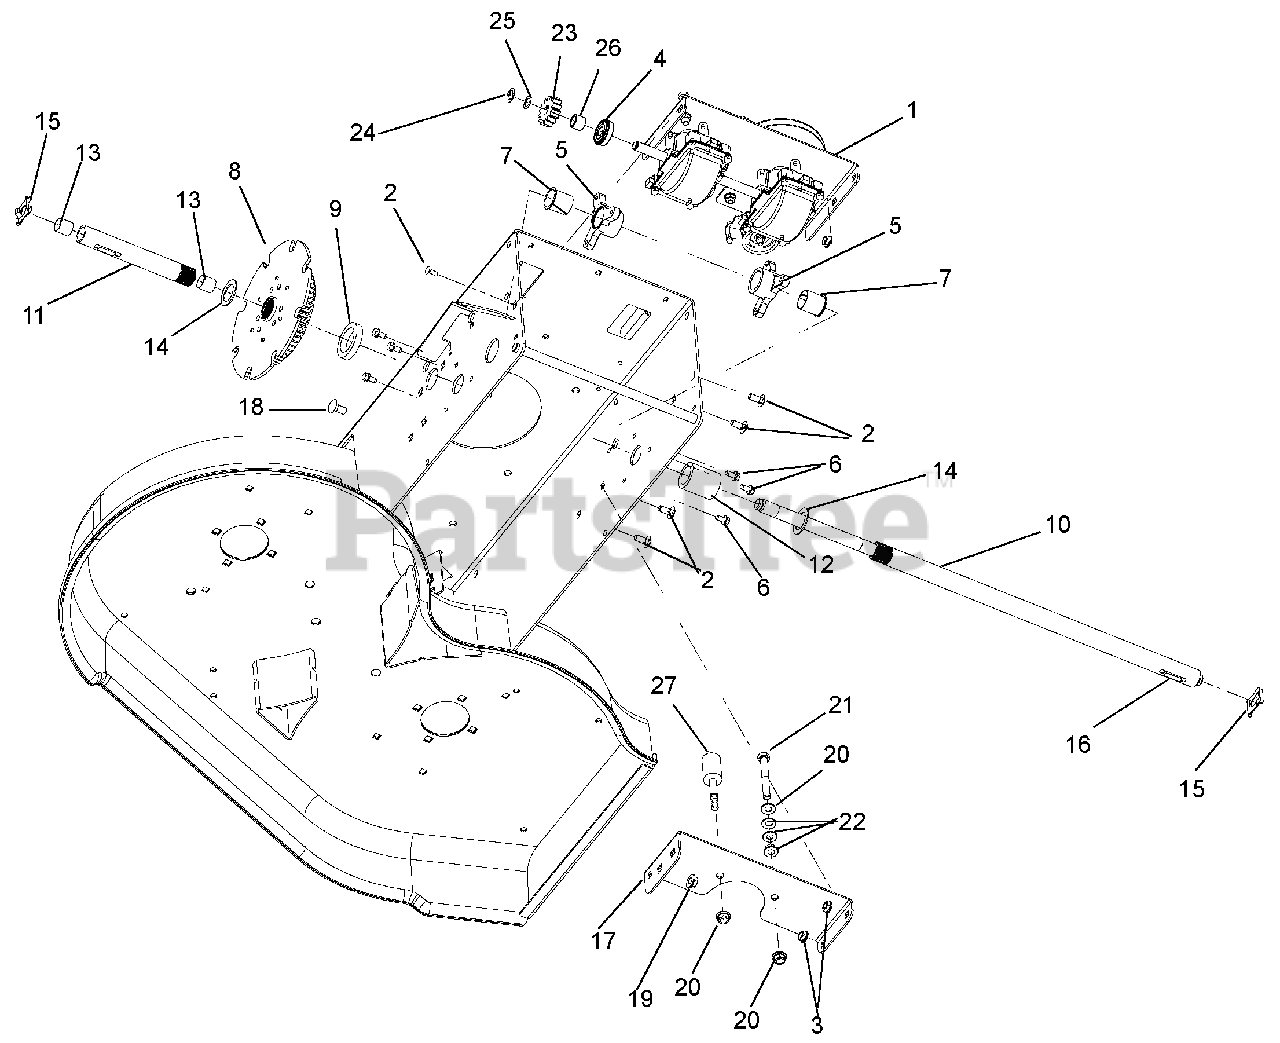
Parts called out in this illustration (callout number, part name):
1	KIT, WAW TRANSMISSION
2	@BLT-RDHDSQNK .31-18X.75 G5YZ
3	@NUT-LK-TOP-FLG .31-18 YWZC
4	BRG-BALL .50X1.38X.438 SEALED
5	BUSHING, RAKE SHAFT 1"
6	@SCR-TAP .25-20X.50 HWH TR YWZ
7	BSHG-FLG SPLIT NYLINER 1.0" HP
8	KIT, WAW DIFFERENTIAL
9	WSHR-FL-NY 1.42X2.03X.35
10	SHAFT-AXLE LONG
11	SHAFT-AXLE, SHORT
12	SPACER, 1.0X1.5X1.57
13	BSHG-SLV .706X.764X.75 BRZ
14	WSHR-FL-STL 1.010X1.505X.062YZ
15	CLIP, SNAP .625 DIA
16	KEY-RECT .25X.188X1.00
17	BRKT, BELT FINGER MOUNTING
18	@BLT-RDHDSQNK .38-16X.75 G5YZ
18	@BLT-RDHDSQNK .31-18X.75 G5YZ
19	@NUT-LK-TOP-FLG .38-16 YWZC
19	@NUT-LK-TOP-FLG .31-18 YWZC
20	@NUT-SPNLK-FLG .375-16 YWZC
21	BLT-HEX .38-16X3.00 GR5 FTH YZ
22	WSHR,FLT STL.406X1.50X.245YWZC
23	PINION, TRANSMISSION DRIVE
24	RG-RTNG-EXT .500X.042 (E)
25	WASHER, .500X.750X.020 THRUST
26	RETAINER, BEARING
27	BELT FINGER
